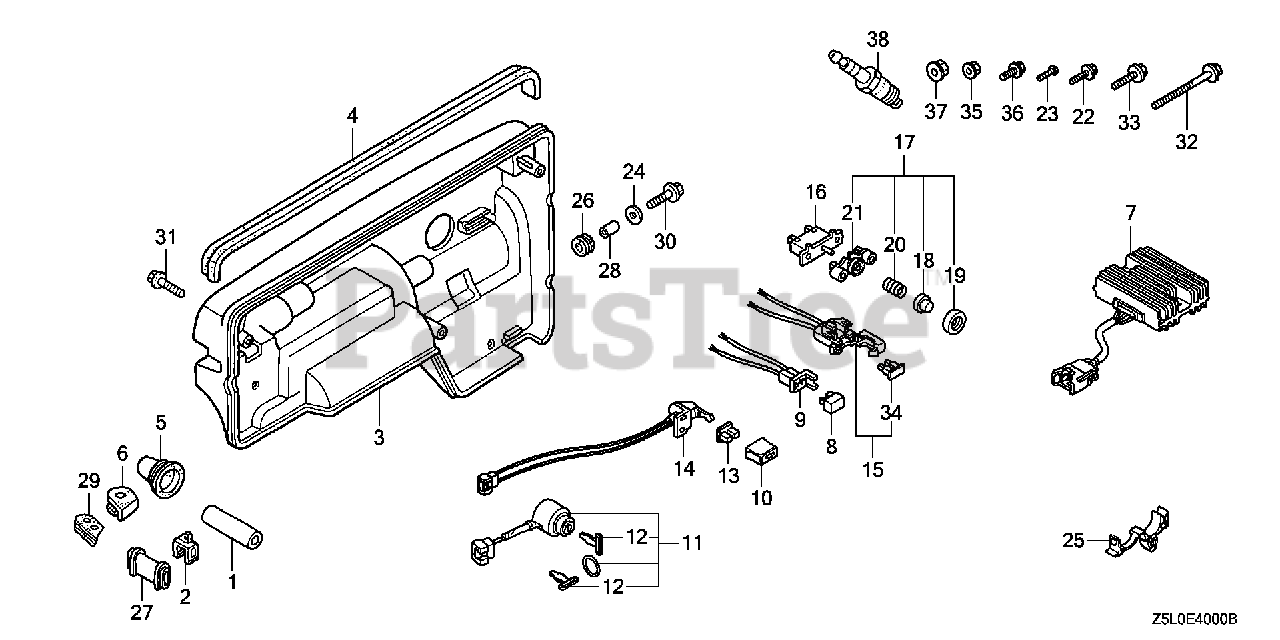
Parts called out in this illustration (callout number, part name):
8	RECTIFIER ASSY., SILICON (SHINDENGEN)
11	SWITCH ASSY., COMBINATION
12	KEY
15	CASE, FUSE
22	BOLT, FLANGE (6X12) (CT200)
34	FUSE, BLADE (10A)
35	NUT, FLANGE (5MM)
36	BOLT, FLANGE (6X10)
